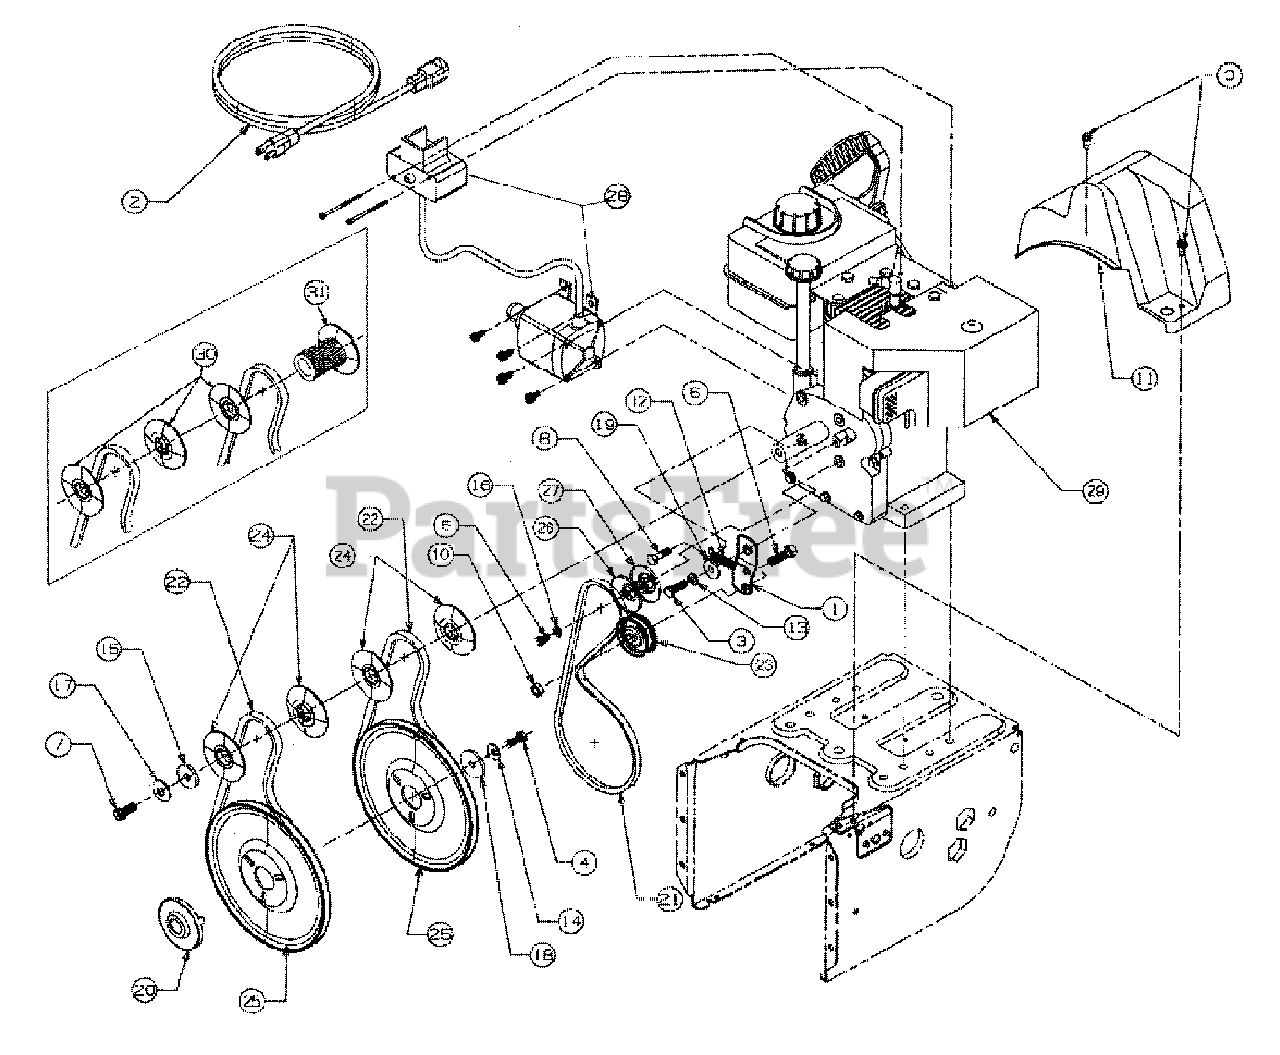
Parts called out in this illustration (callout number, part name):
3	Screw
4	Screw
5	Screw
6	Screw
7	Screw
8	Screw
9	Screw
10	Nut, Hex
11	Belt Cover
12	Spring
13	Washer-Flat
14	Washer-Bell
15	Washer-Flat
16	Washer-Lock
17	Washer-Bell
18	Washer-Flat
19	Shoulder Spacer
20	Pulley, Adapter
21	V-Belt
22	V-Belt Matched
23	Idler, Flat
24	Pulley, Half
25	Pulley-Auger
26	Pulley Half
27	Pulley Half
28	Starter (633)
28	Starter
29	Engine
30	Pulley, Half (633)
31	Pulley, Half (633)
